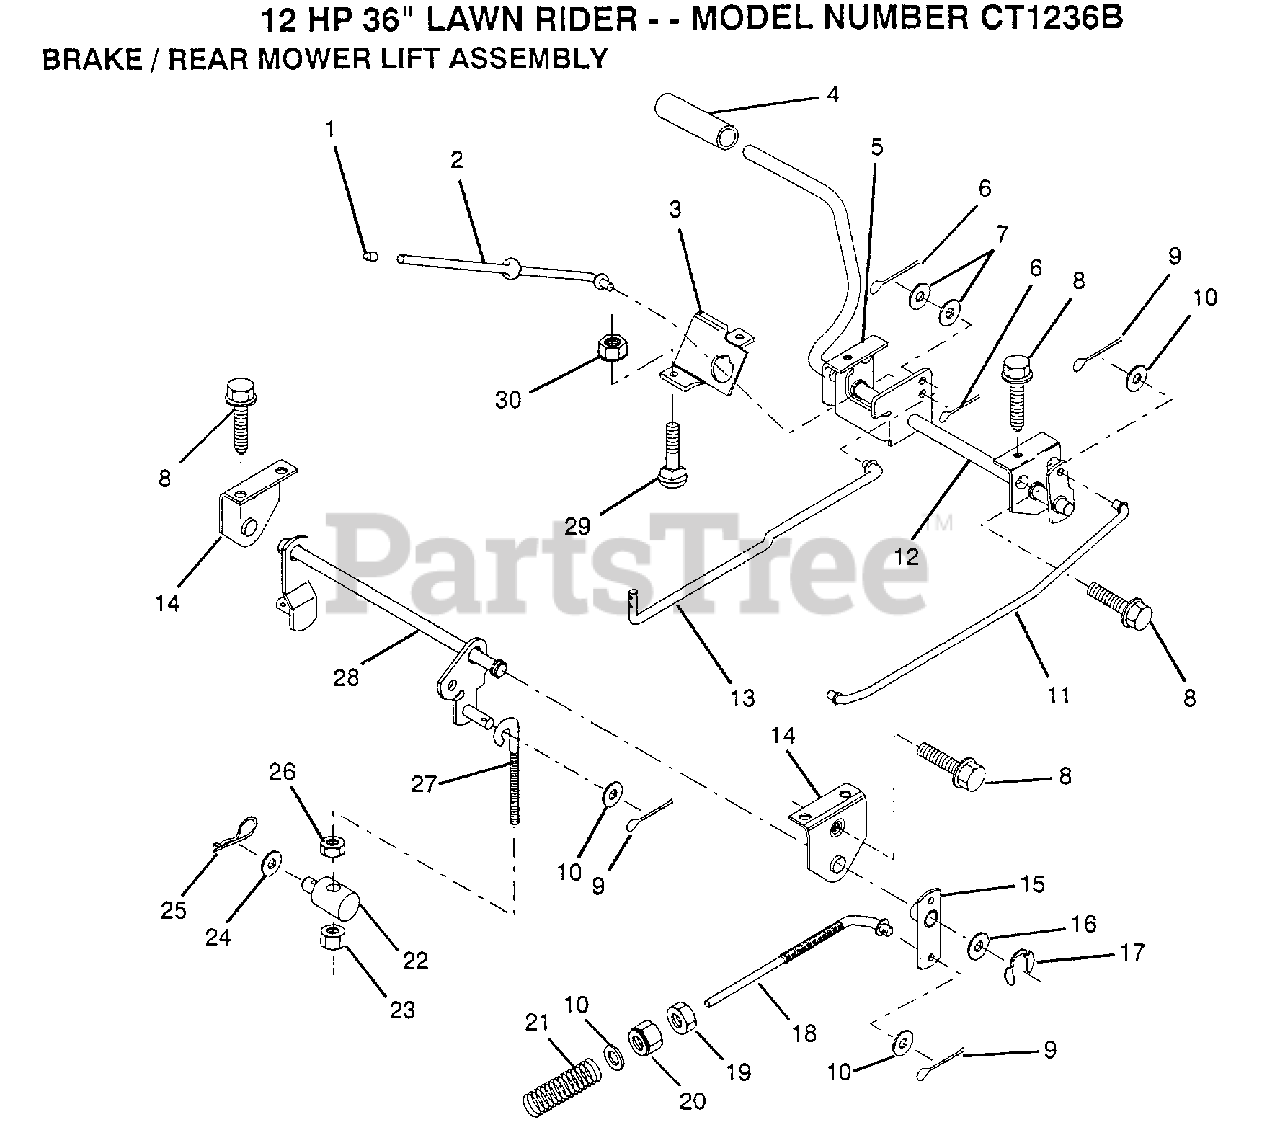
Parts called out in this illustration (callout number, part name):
1	PLUNGER CAP T
2	"ROD,PARK BRAKE"
3	"BRKT,PARK BRAKE"
4	PEDAL COVER T
5	"BRKT,CLU PEDAL LH"
7	WASHER
8	SCREW LT
9	COTTER PIN
10	WASHER
11	"ROD,FRT BRAKE"
13	"ROD,CLUTCH"
14	"BRKT,LIFT SHAFT"
15	BRAKE PIVOT ARM
16	WASHER T
17	KLIP RING
19	NUT
20	NUT
21	SPRING ROD LT
24	WASHER
25	SPRING.RETAINER
26	LOCKNUT
27	"LINK, MOWER REAR"
